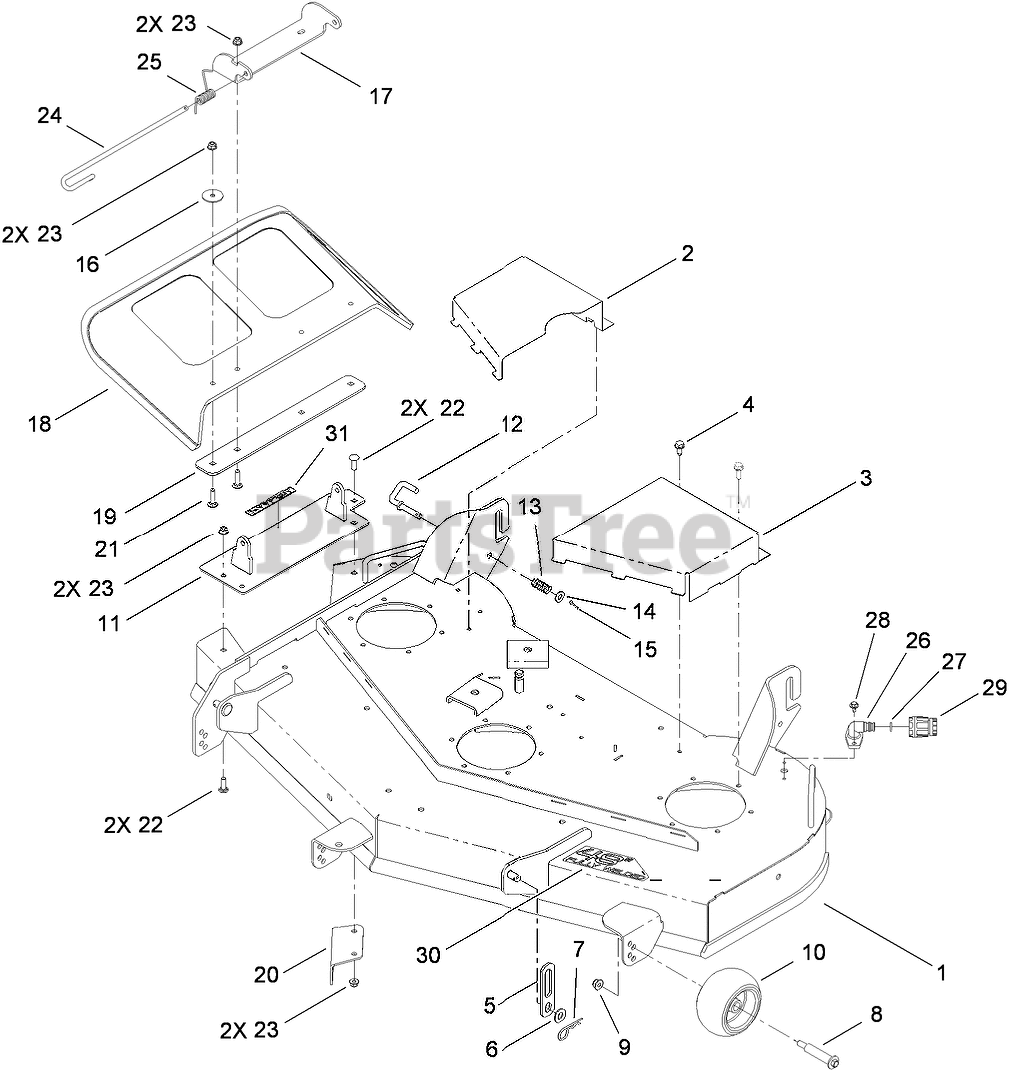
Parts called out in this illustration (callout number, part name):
1	48 INCH DECK AND DECAL ASM
2	COVER-BELT, RH
3	COVER-BELT, LH
4	SCREW-HWHTF
5	LINK-LIFT
6	WASHER-FLAT
7	PIN-COTTER
8	BOLT-SHOULDER
9	NUT-HF, NI
10	ROLLER-SCALP, ANTI
12	PIN-LATCH
13	SPRING-COMPRESSION
14	WASHER-FLAT
15	PIN-COTTER
16	WASHER-FLAT
17	BRACKET-DEFLECTOR, UPPER
18	DEFLECTOR
19	PLATE-DEFLECTOR
20	BAFFLE-CUTOFF
21	SCREW-CARR
22	SCREW-CARR
23	NUT-HF, NI
24	PIN-CHUTE
25	SPRING-TORSION
26	FITTING-WASHOUT
27	O-RING
28	SCREW-HHFTF
29	CONNECTOR-HOSE
30	DECAL-DECK
31	DECAL-DANGER
